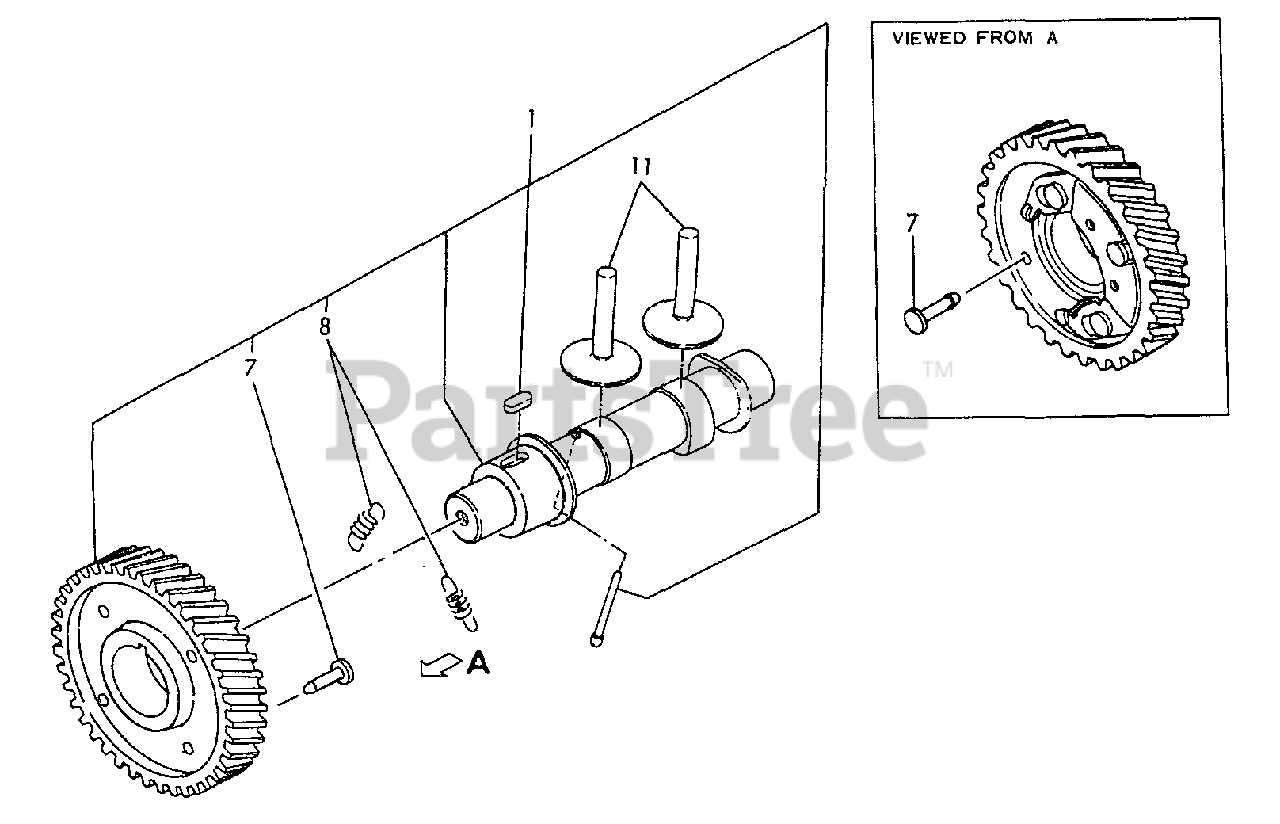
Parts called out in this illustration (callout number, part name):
1	CAMSHAFT ASSY
7	PIN (B), GUIDE
8	SPRING, DECOMP.
11	TAPPET
